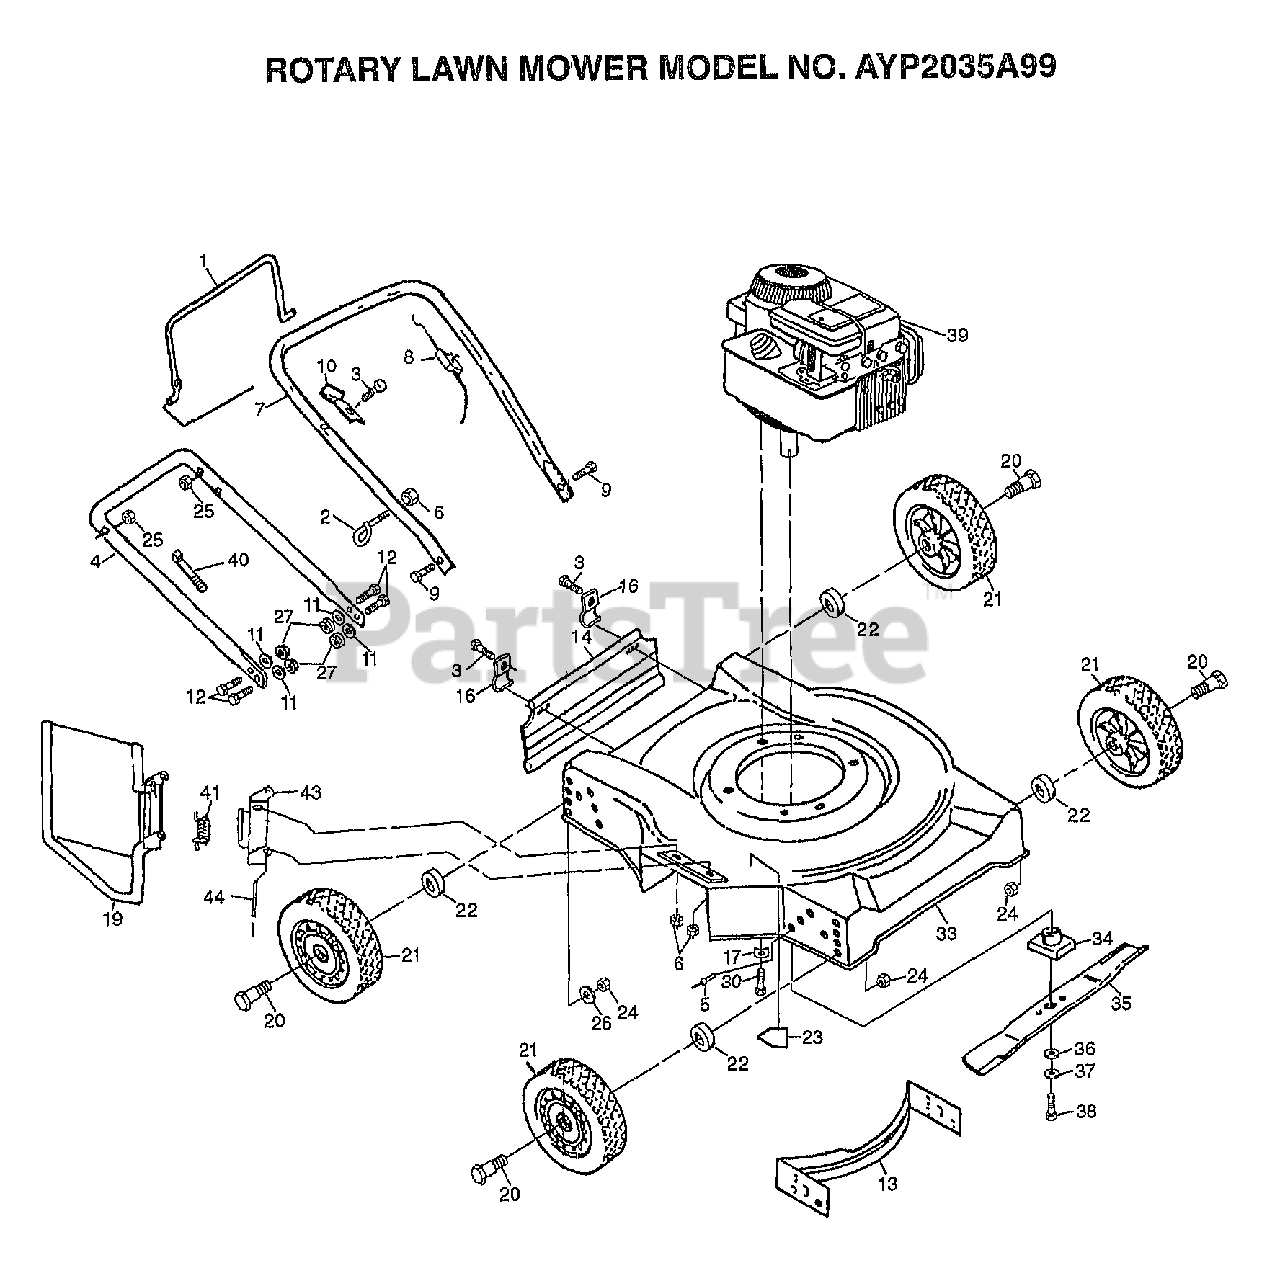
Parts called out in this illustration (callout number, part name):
1	CONTROL BAR PM
2	ROPE GUIDE
3	TAPPING SCREW
4	HANDLE.LOWER.PUSH.16
5	BLIND RIVET
7	HANDLE.UPPER.ECON.
8	ENG ZONE CTRL CAB
9	BOLT 1/4-20-1 1/2
10	"BRKT,UPSTOP"
11	STEEL WASHER
14	SKIRT.REAR.20RD.
16	"BRKT,DEFL PM"
19	"GRD,DISCHARGE"
20	AXLE BOLT
21	WHEEL&TIRE
23	DECAL-DANGER PM
24	LOCKNUT PM
27	LOCKNUT
30	BOLT.ENG.3/8-16
33	KIT.HSG.20SD.PUSH
34	BLADE ADAPTOR
35	BLADE.20.MULCH.AY
36	"WASHER,HARDEN"
37	LOCKWASHER
38	SCREW
41	"SPRING,TORSION"
43	HINGE DEFLECTOR
44	HINGE ROD
